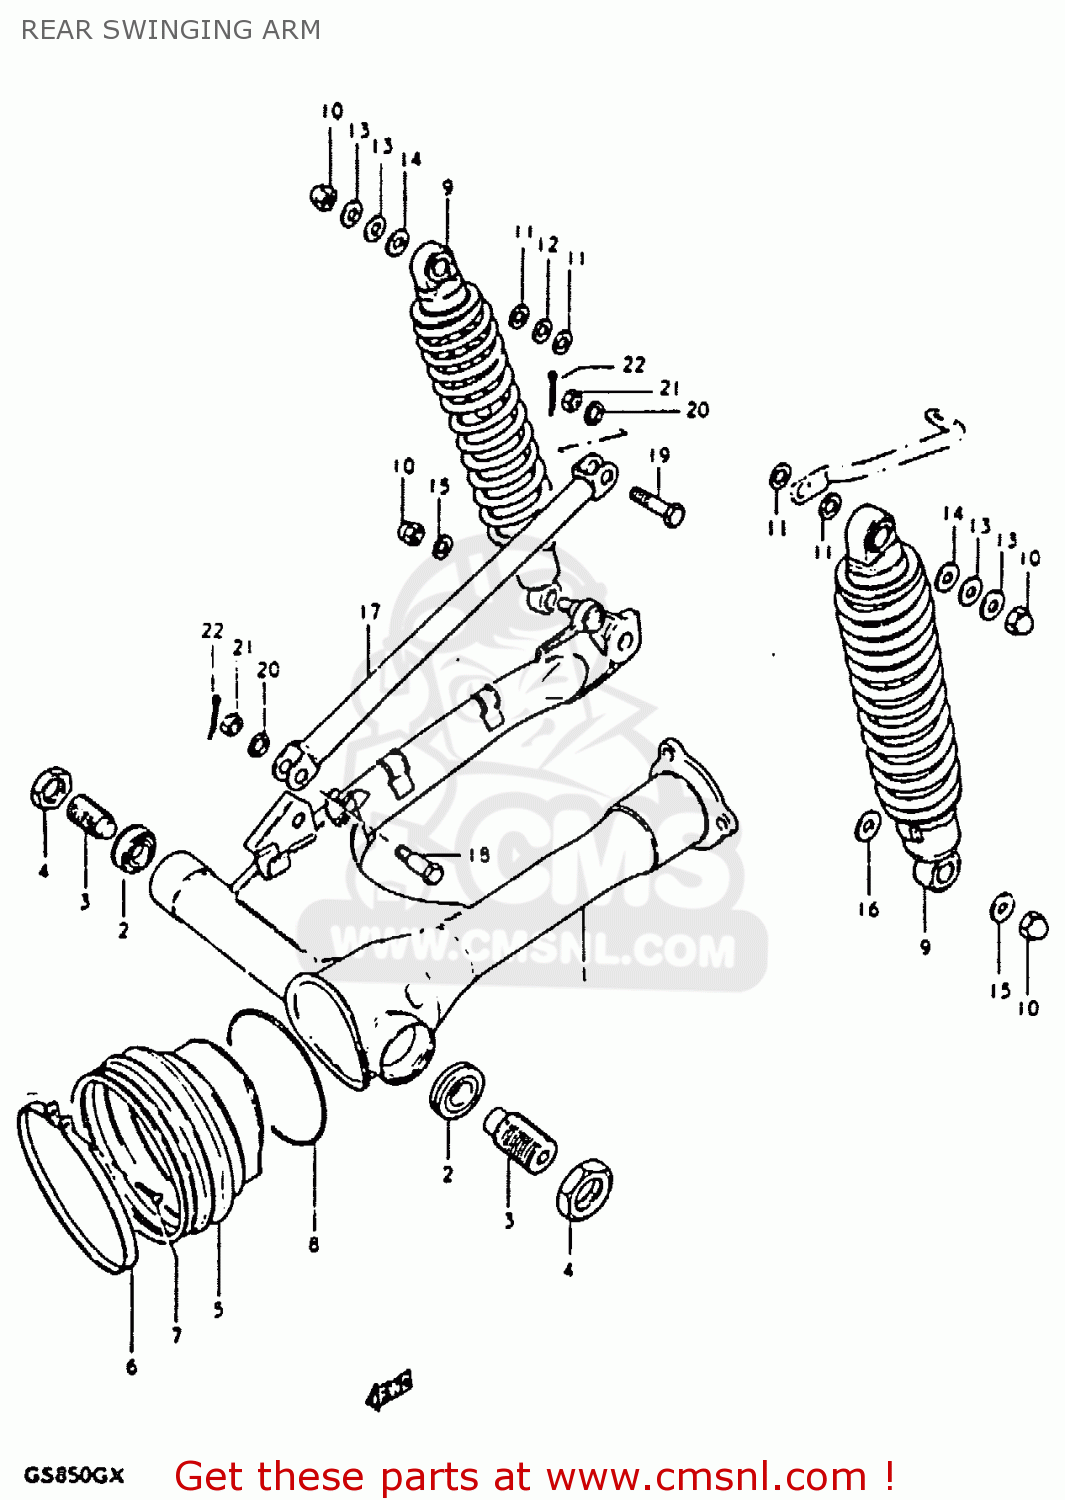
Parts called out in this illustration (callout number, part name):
1	SWING ARM ASSEMBLY,REAR
2	BEARING(17X40X13.25)
3	BOLT,REAR SWING ARM PIVOT
4	NUT
5	BOOT,PROPELLER SHAFT
6	CLAMP
7	SCREW 4X25
8	SPRING,PROPELLER SHAFT
9	SHOCK ABSORBER, REAR
10	NUT, LOWER LH
11	WASHER
12	WASHER (12.5X24X3.2)
13	WASHER
14	WASHER(10.5X24X3.2)
15	WASHER
16	WASHER
17	LINK,REAR TORQUE
18	BOLT
19	BOLT(10X39)
20	WASHER
21	NUT
22	PIN 20X20
